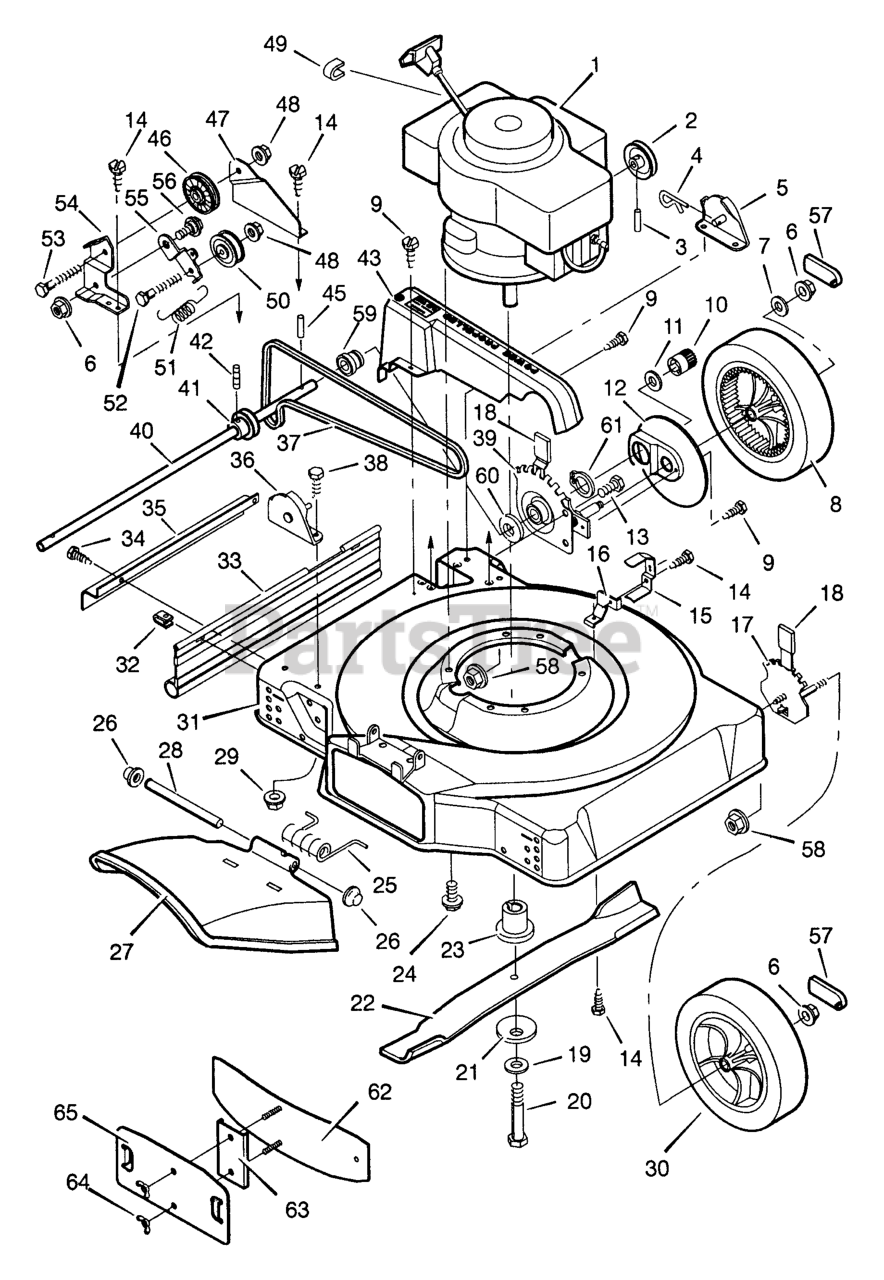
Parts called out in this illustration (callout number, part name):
2	Pulley
3	Pin, Spring
4	Pin, Hair
5	Bracket, Left Handle
6	Nut
7	Washer
8	Wheel, Drive
10	Gear, Right Pinion
12	Cover, Dust
13	Bolt, Hex
15	Guide, Belt
16	Belt Guide, Briggs
17	Height Adjuster, Front
21	Washer, Belleville
23	Adapter, Blade
24	Bolt, Engine
25	Spring, Torsion
26	Push On Cap
27	Deflector, Chute
29	Nut
30	Wheel and Tire, Front
31	Housing
32	Retainer
33	Deflector, Rear
35	Guard, Axle
36	Bracket, Right Handle
37	Belt, Briggs & Stratton
39	Height Adjuster, Left
41	Axle, Pulley & Setscrew
42	Setscrew
43	Belt Guard, Briggs
45	Pin, Drive
46	Pulley, Idler
47	Support, Idler
48	Nut
49	Stop, Rope
50	Pulley, Idler
51	Spring, Extension
52	Bolt, Hex
53	Bolt, Hex
54	Bracket, Idler
55	Arm, Idler
56	Bolt, Shoulder
57	Cap, Hub
58	Nut, Flange
59	Bearing and Retainer
60	Washer, Belleville
61	Retainer Ring
64	Wingnut
